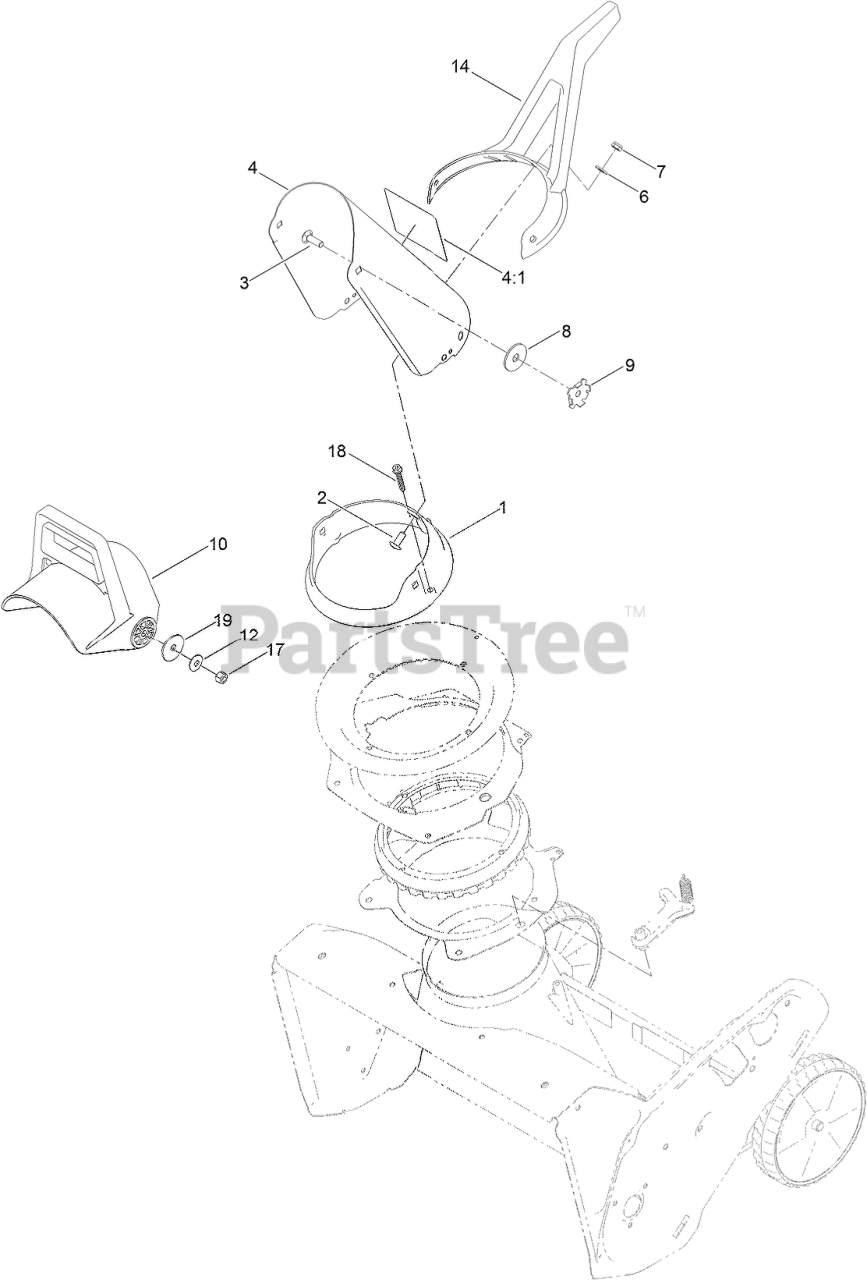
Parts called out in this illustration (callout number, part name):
1	RING-CHUTE
2	SCREW-PTH
3	SCREW-CARR
4	DISCHARGE CHUTE ASM
4:1	DECAL-DANGER, CE
6	WASHER-FLAT
7	NUT-LOCK, NI
8	WASHER-RUBBER
9	PLATE-FRICTION
10	CHUTE-DEFLECTOR
12	WASHER-BELLEVILLE
14	HANDLE-CONTROL, CHUTE
17	NUT-HEX
18	SCREW-PLASTITE
19	WASHER-FLAT
